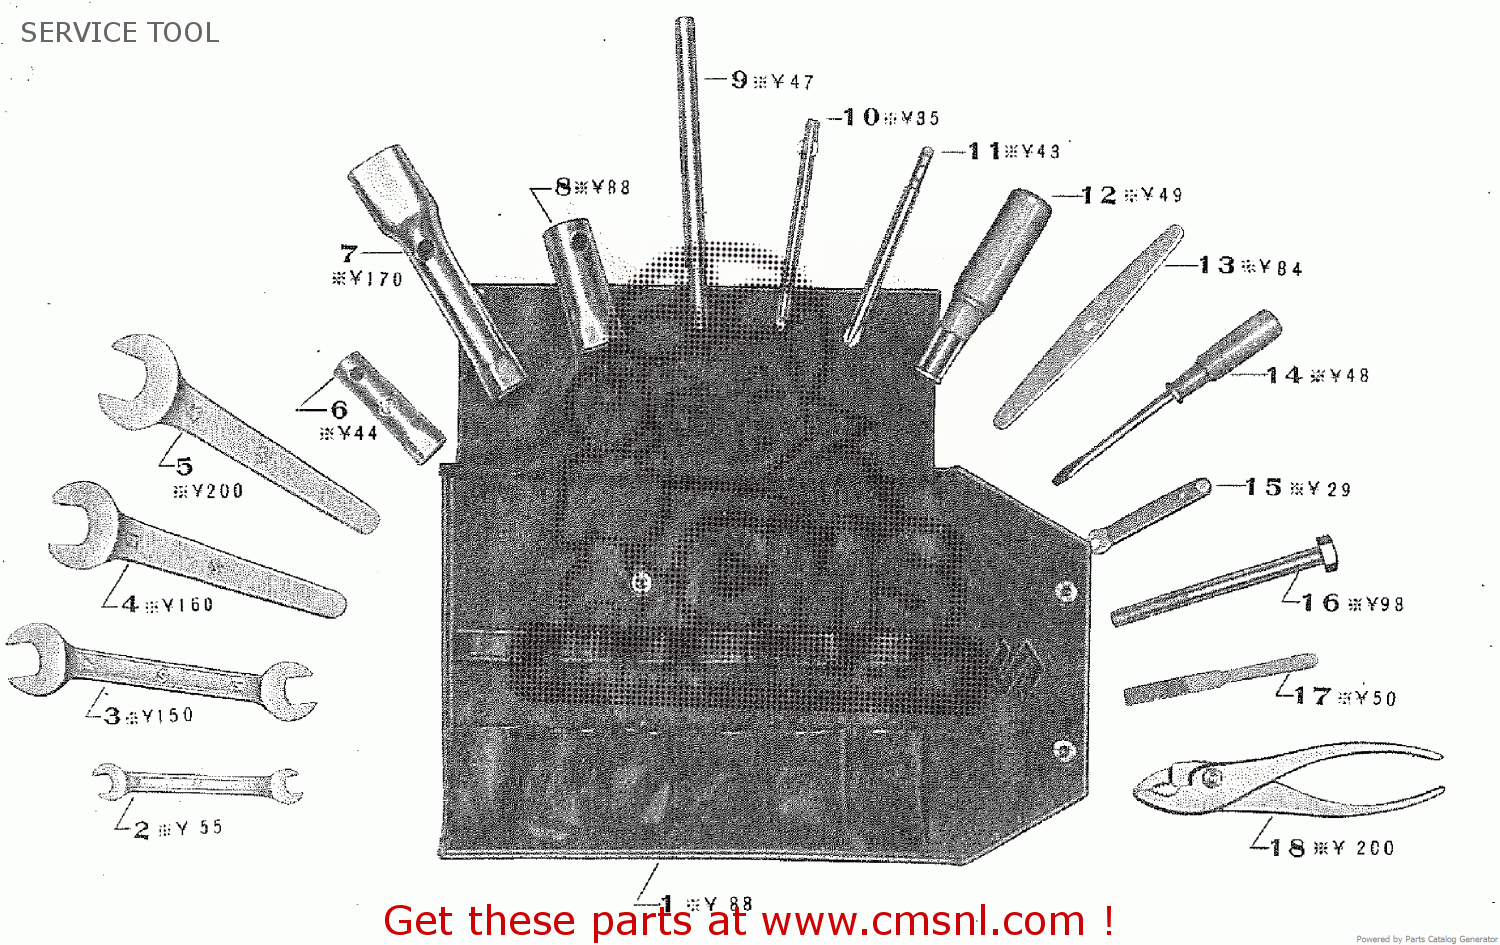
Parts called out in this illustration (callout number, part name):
1	TOOL BAG
2	SPANNER WRENCH
3	SPANNER WRENCH
4	SPANNER WRENCH
5	SPANNER WRENCH
6	BOX SPANNER
7	BOS HANDLE
8	BOX SPANNER
9	BOX SPANNER HANDLE
10	CROSS SCREW DRIVER
11	CROSS SCREW DRIVER
12	DRIVER CLIP
13	DRIVER HANDLE
14	SCREW DRIVER
15	POINT SPANNER
16	AMATEUR REMOVE BOLT
17	POINT FILE
18	PLIER
